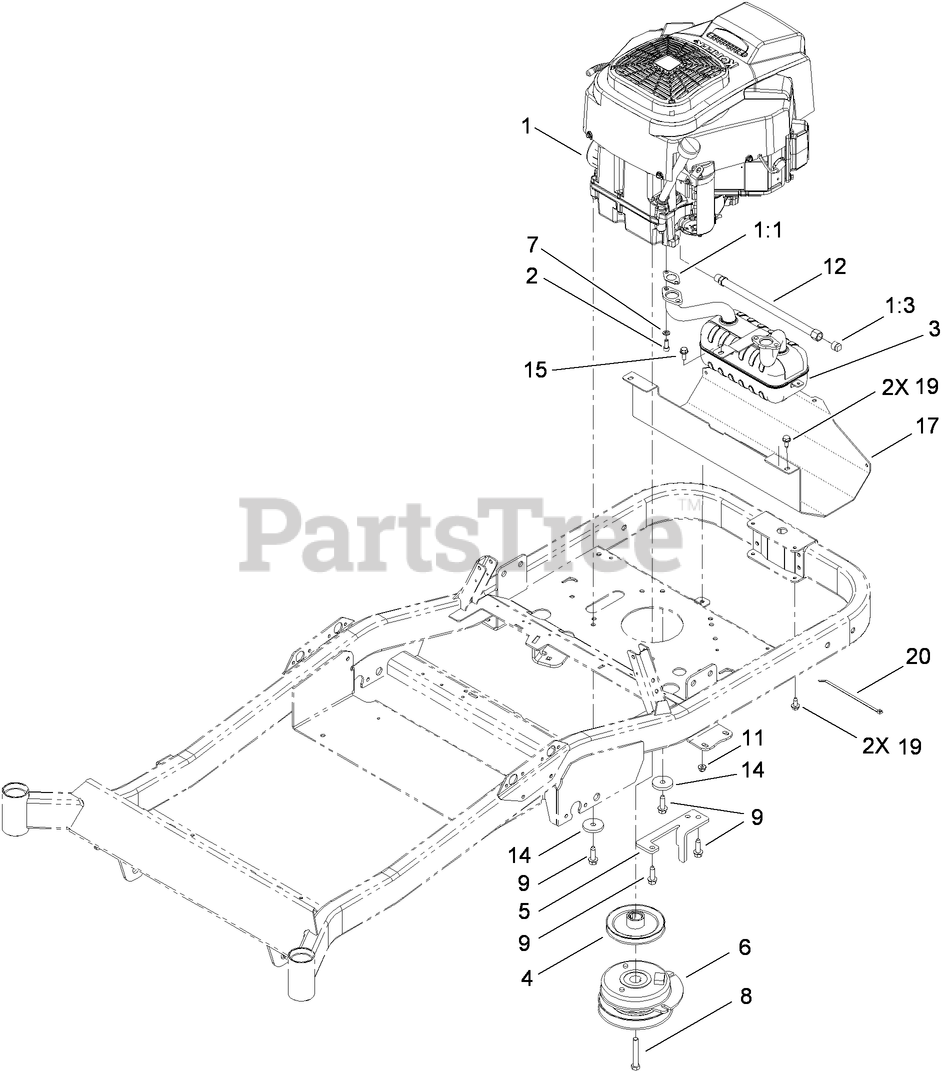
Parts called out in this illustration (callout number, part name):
1:1	GASKET-EXHAUST
1:3	PLUG-PIPE, SQH
2	SCREW-HSH
3	MUFFLER-TWIN, KOHLER
5	BRACKET-STOP, PTO
6	CLUTCH-PTO
7	WASHER-LOCK
8	SCREW-HH
9	SCREW-THD
11	NUT-HF, NI
12	HOSE-DRAIN, OIL
14	WASHER-PLAIN
15	SCREW-HHF
17	SHIELD-HEAT
19	SCREW-HWHTF
20	TIE-CABLE
